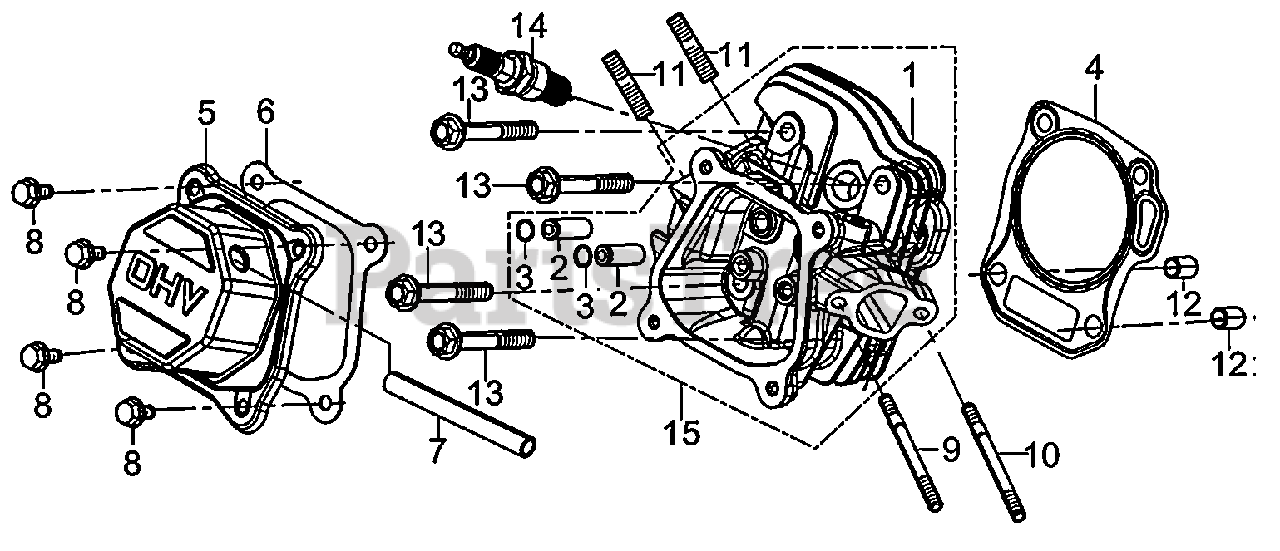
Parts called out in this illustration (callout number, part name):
4	GASKET, CYLINDER HEAD
5	COVER SUBASSEMBLY, CYLINDER HEAD
6	GASKET, CYLINDER HEAD COVER
7	TUBE, BREATHER
12	PIN, DOWEL
13	BOLT, CYLINDER HEAD
14	PLUG, SPARK
15	HEAD SUBASSEMBLY, CYLINDER
